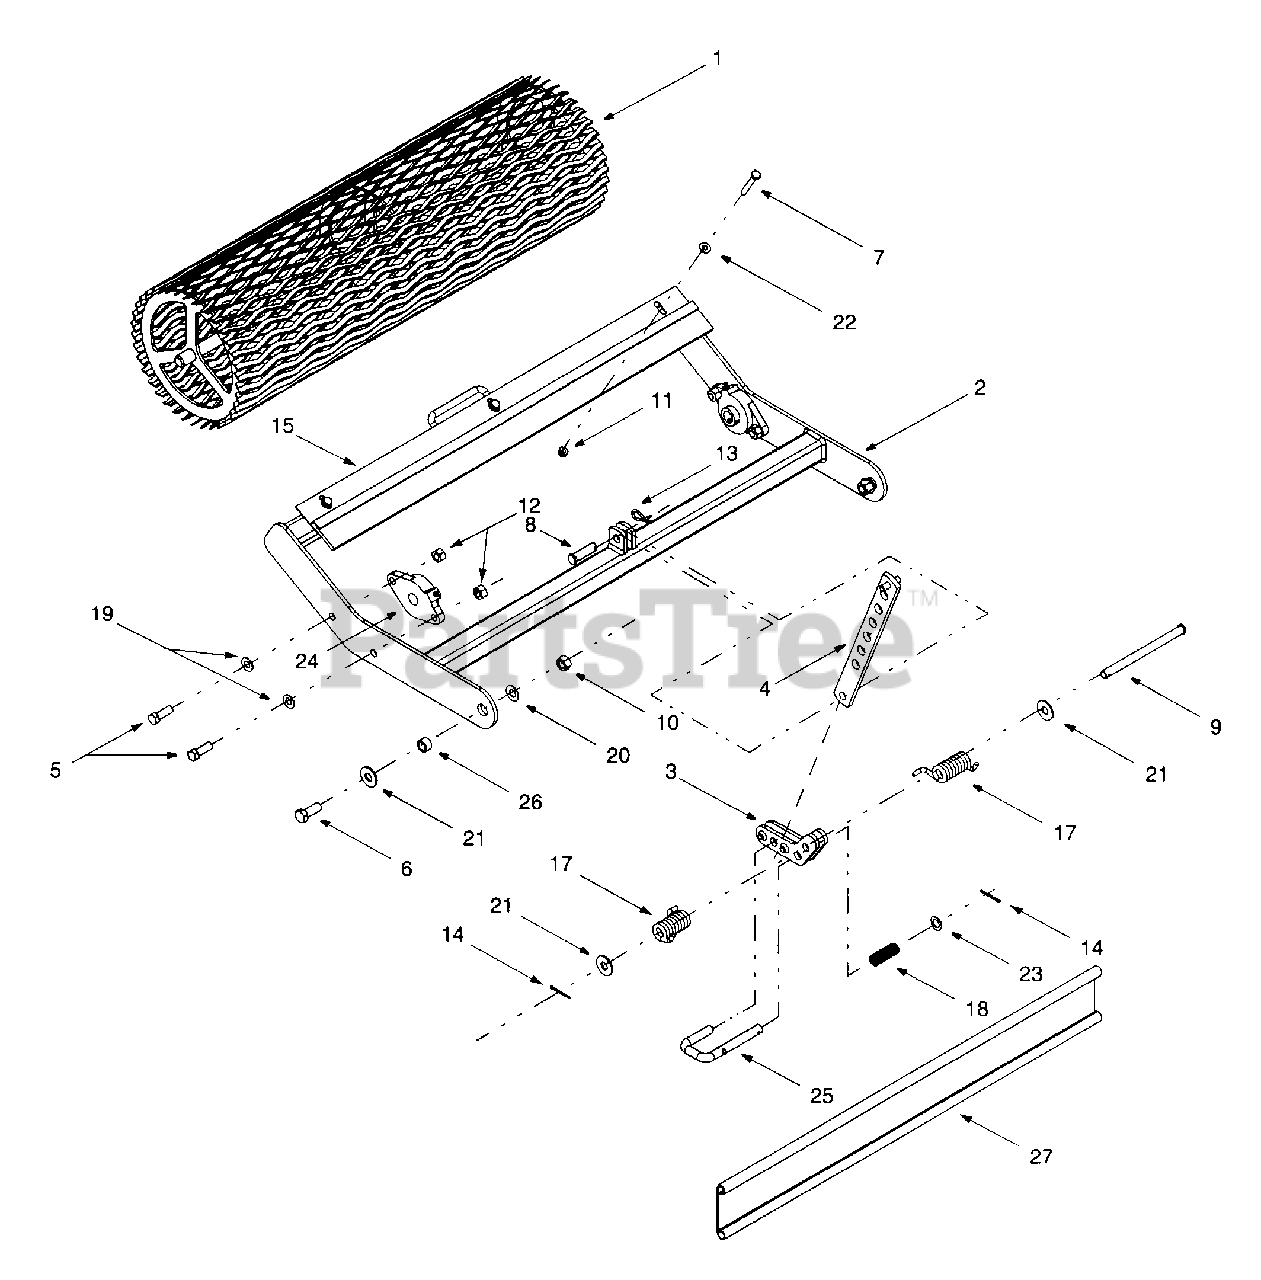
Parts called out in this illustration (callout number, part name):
1	30-inch Roller Assembly
2	Roller Frame Assembly
3	Roller Bracket Assembly
4	Lock Pivot Plate Assembly
5	Hex Cap Screw, 7/16-20 x 1.25
6	Hex Cap Screw, 1/2-13 x 1.25
7	Hex Cap Screw, 5/16-18 x 2.0
8	Clevis Pin, .50 x 1.59
9	Clevis Pin, .50 x 6.5
10	Hex Nut, 1/2-13
11	Hex Lock Nut, 5/16-18
12	Hex Lock Nut, 7/16-20
13	Internal Cotter Pin
14	Cotter Pin, 1/8 x 1.25
15	30-inch Roller Brush
16	RH Torsion Spring
17	LH Torsion Spring
18	Compression Spring, .57 x 2.09
19	Flat Washer, .474 x .879 x .064
20	Belleville Washer
21	Flat Washer, .344 x .688 x .065
22	Flat Washer, .536 x 1.262 x .101
23	Flat Washer, .50 x .875 x .060
24	Flange Bearing, .75
25	Roller Locking Rod
26	Spacer, .51 x .75 x .44
